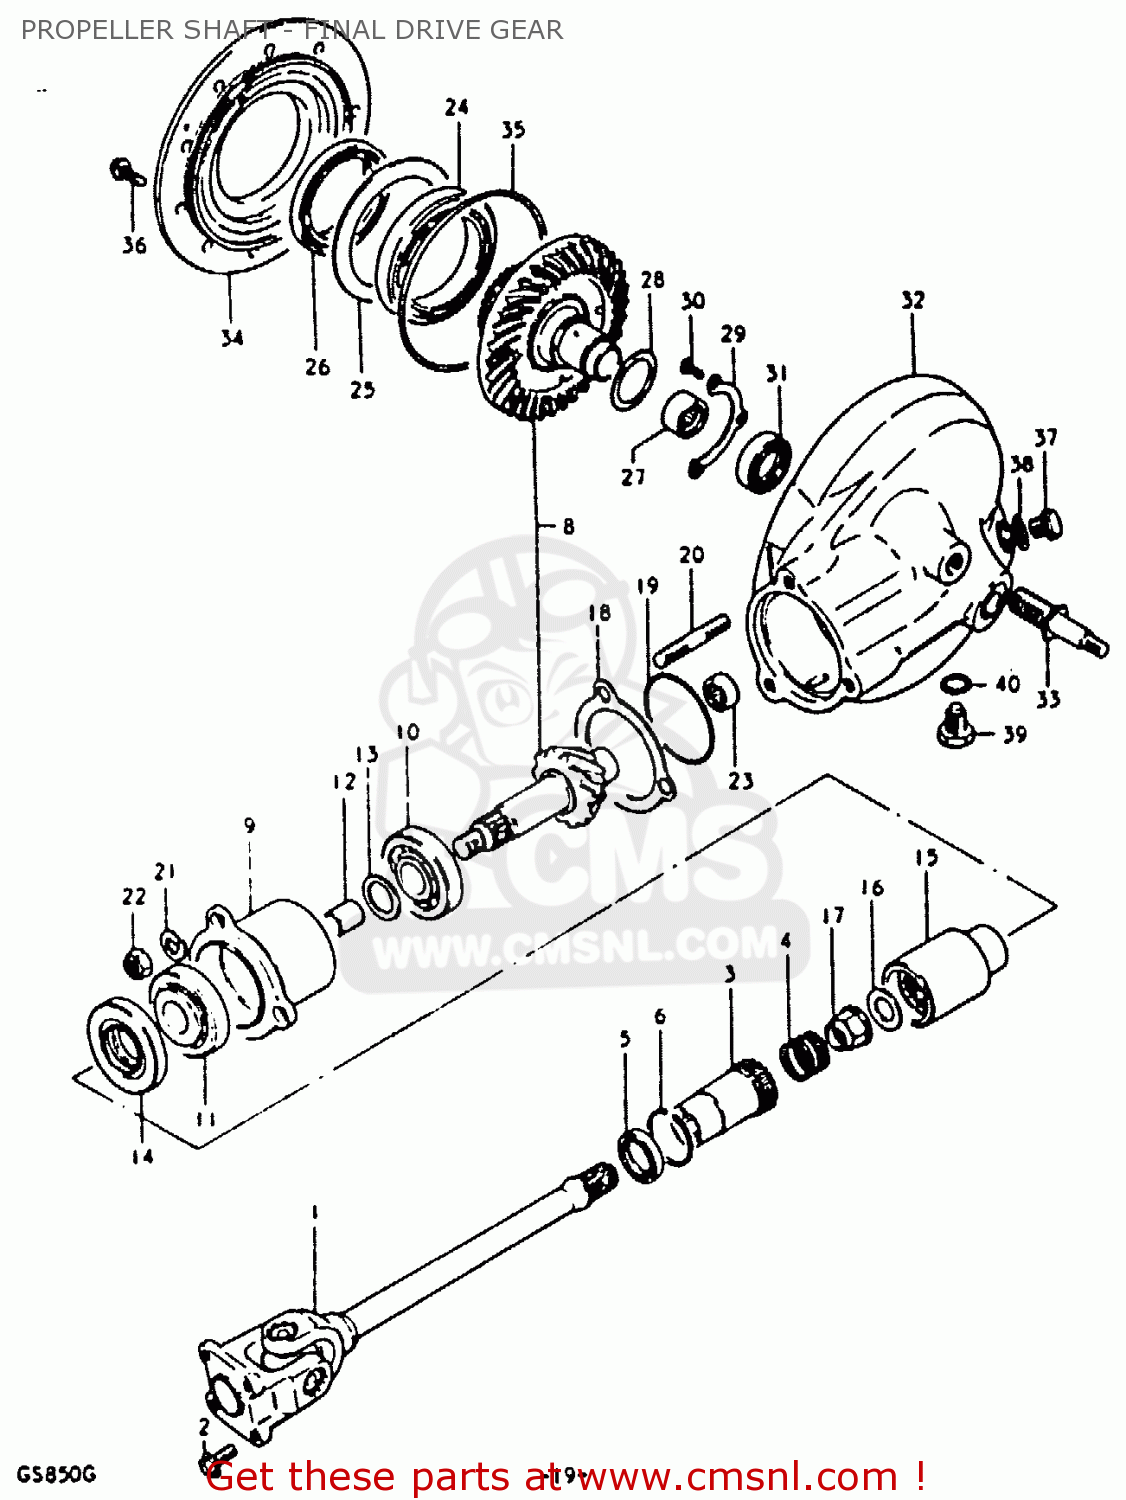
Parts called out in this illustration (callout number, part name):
1	SHAFT ASSEMBLY,PROPELLER
2	BOLT 8X16
3	COUPLING,PROPELLER SHAFT
4	SPRING
5	SEAL,OIL(30X40.5X5.5)
6	CIRCLIP
7	FINAL BEVEL GEAR & CASE
8	GEAR SET,FINAL BEVEL
9	HOUSING,DRIVE GEAR
10	BEARING(25X52X19.25)
11	BEARING
12	SPACER (25.2X30X3.5)
13	SHIM (25X30X2
14	SEAL,OIL(32X54X7)
15	GEAR,FINAL DRIVE
16	WASHER(14X29X4)
17	NUT
18	SHIM,DRIVE GEAR HOUSING
19	O RING(D:2.4,ID:62.6)
20	STUD 10X30
21	LOCK WASHER
22	NUT
23	BEARING(24X33X17)
24	BEARING(70X110X13)
25	SHIM,DRIVEN GEAR BEARING
26	SEAL,OIL(70X96X16)
27	BEARING(35X48X23.7)
28	SHIM,FINAL DRIVEN GEAR
29	RETAINER,FINAL DRIVEN GEAR BRG
30	SCREW 6X12
31	SEAL,OIL(30X42X7)
32	CASE ASSEMBLY,FINAL GEAR
33	STUD
34	CASE,FINAL GEAR BEARING
35	O-RING (D:3.1 ID:144.4)
36	BOLT
37	PLUG (14X12)
38	GASKET(14X19.2X2) (NAS)
39	PLUG
40	GASKET(14X19.2X2) (NAS)
